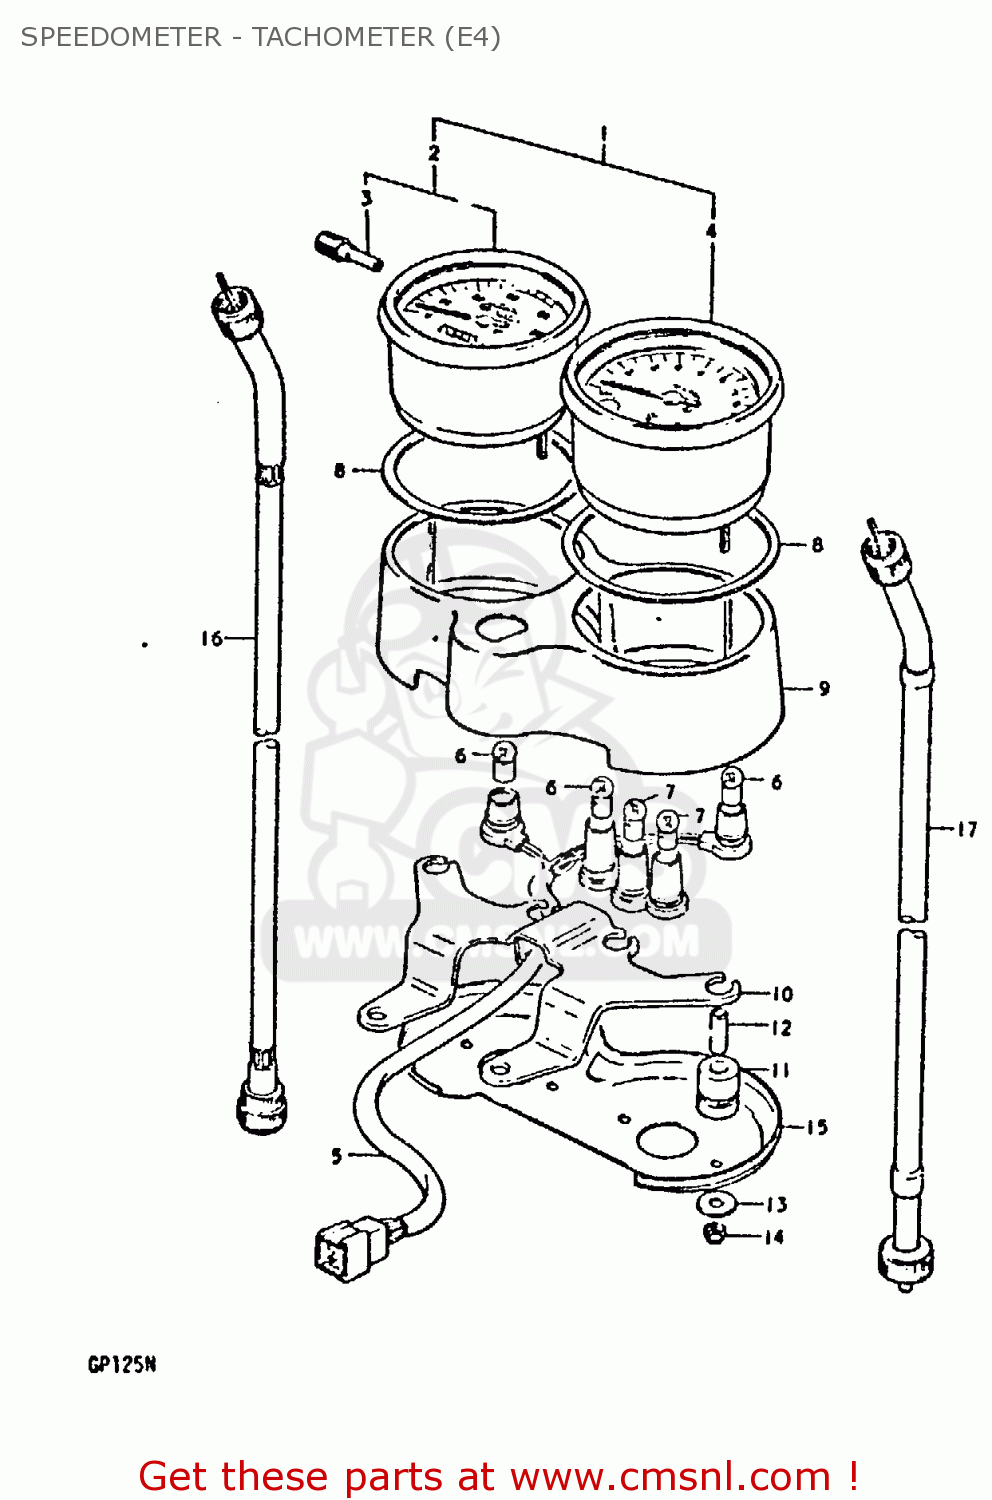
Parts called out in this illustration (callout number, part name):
1	SPEEDO/TACHOMETER ASSY
2	SPEEDOMETER ASSY
3	KNOB,TRIP METER
4	TACHOMETER ASSY
5	SOCKET
6	BULB(6V1.7W,STANLEY,A61A)
7	BULB(6V/3W)
8	GASKET, METER
9	CASE, METER
10	BRACKET
11	CUSHION
12	SPACER
13	WASHER,METER
14	NUT
15	UNDER PLATE
16	CABLE ASSY, SPEEDOMETER
17	CABLE ASSY, TACHOMETER
